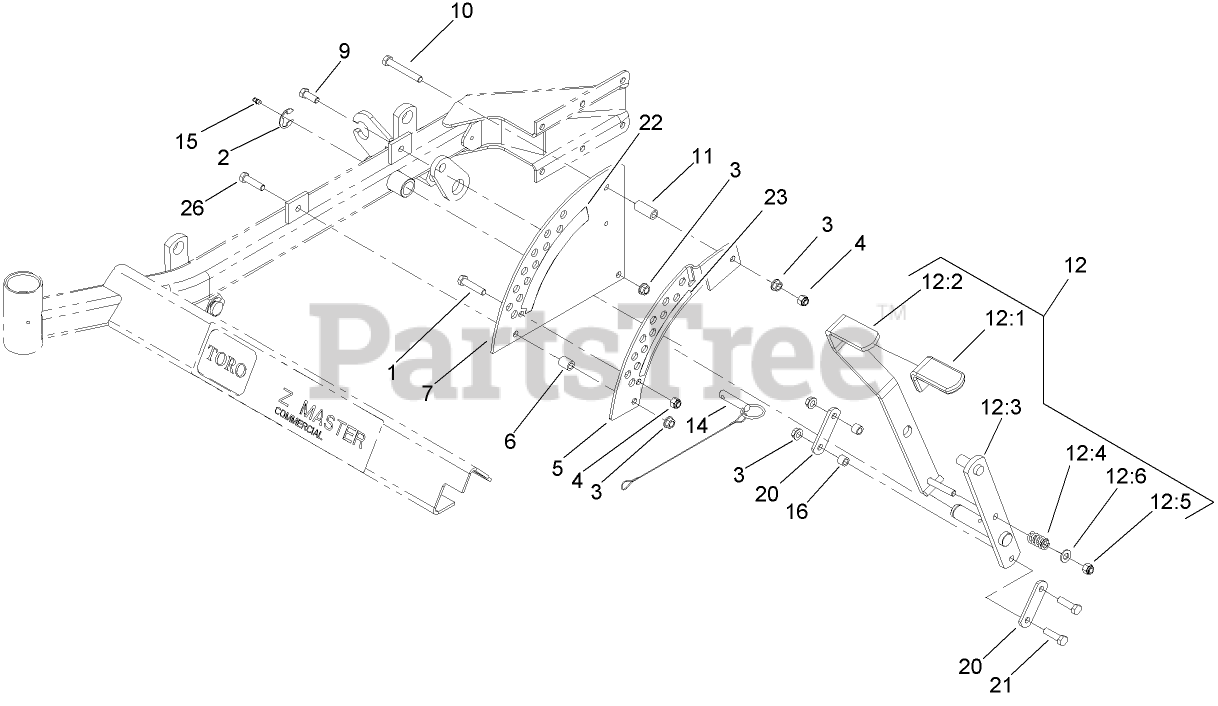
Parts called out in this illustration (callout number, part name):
1	SCREW-HH
2	RING-RETAINING, EXT
3	NUT-HHF, WHIZ
4	NUT-LOCK, NI
5	PLATE-LIFT, DECK
6	BUSHING-LEVER, LIFT
7	PLATE-LIFT, DECK
9	SCREW-HH
10	SCREW-HH
11	BUSHING-LEVER, LIFT
12	DECK LIFT HANDLE ASM
12:1	GRIP-LEVER, LIFT
12:2	HANDLE-LIFT
12:3	LIFT ARM ASM
12:4	SPRING-COMPRESSION
12:5	NUT-LOCK, NI
12:6	WASHER-FLAT
14	Hitch Pin ASM
15	FITTING-GREASE
16	Bushing
20	ARM-LIFT, DECK
21	SCREW-HH
22	DECAL-DECK HEIGHT, OUTER
23	DECAL-DECK HEIGHT, INNER
26	SCREW-HH
